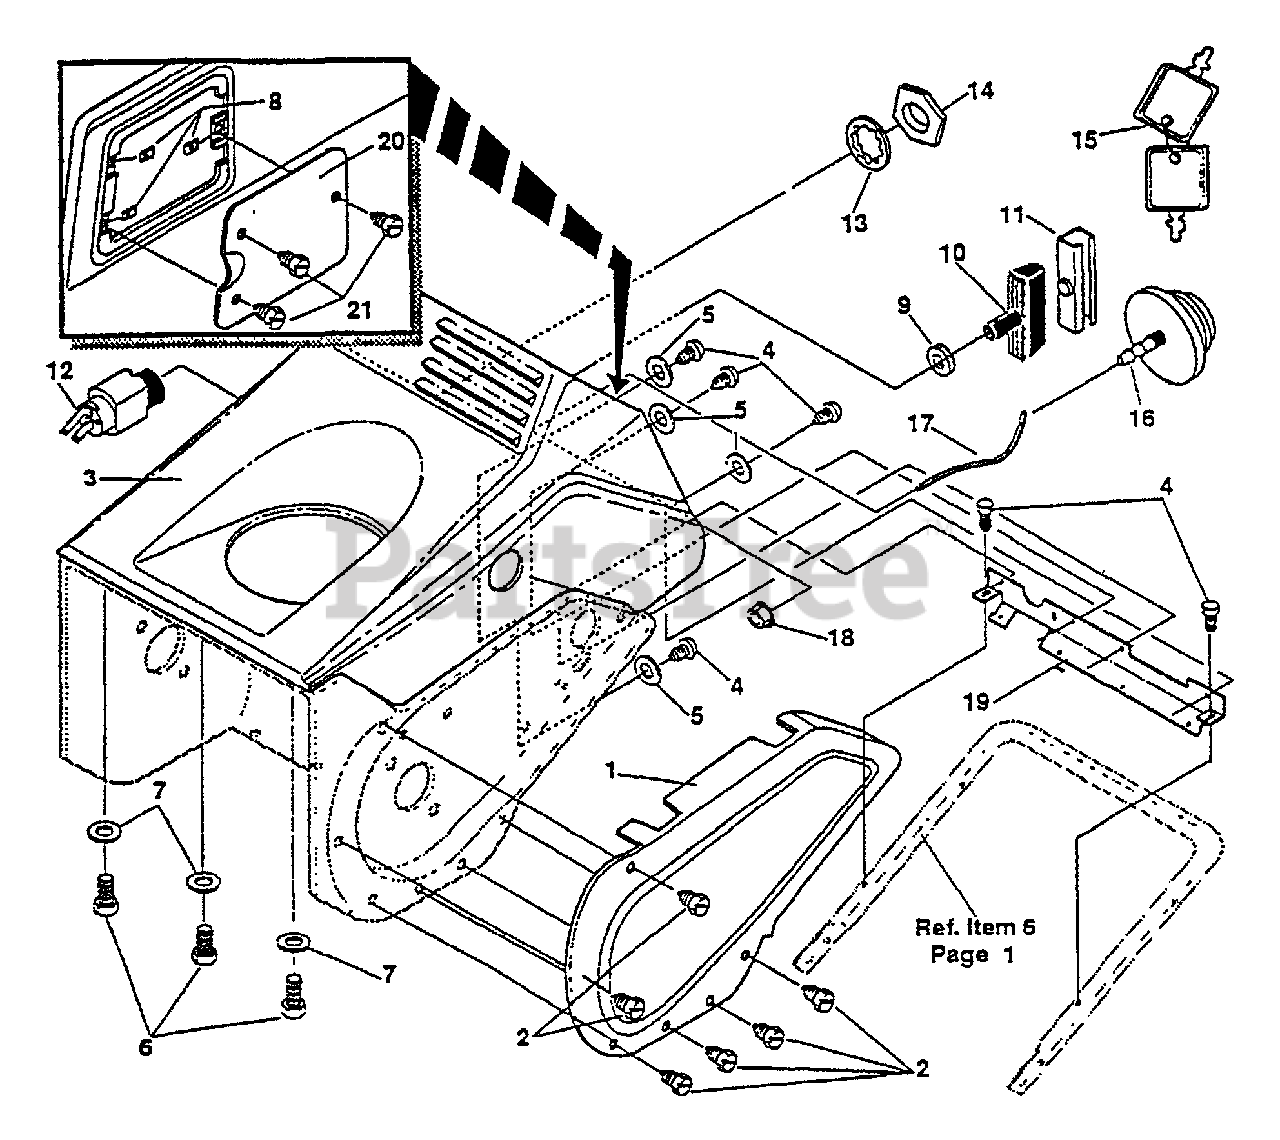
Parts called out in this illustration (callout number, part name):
1	COVER, BELT
2	SCREW
3	COVER - TOP
4	SCREW - 10-24 X .63"
5	WASHER
6	SCREW - 10-14 X .63"
7	WASHER
8	NUT
9	GROMMET & WASHER, ROPE GUIDE
10	KNOB, SHORT SHANK
11	INSERT METAL, KNOB
12	SWITCH, IGNITION
13	WASHER
14	NUT
15	KEYS & RING ASSY
16	PRIMER, ENGINE 2CY
17	HOSE, PRIM 5.75 LONG
18	NUT - 1/4-20 -- KEPS
19	BRACKET, SHROUD MNTG
20	DOOR, ACCESS
21	SCREW - 10-16 X .75"
